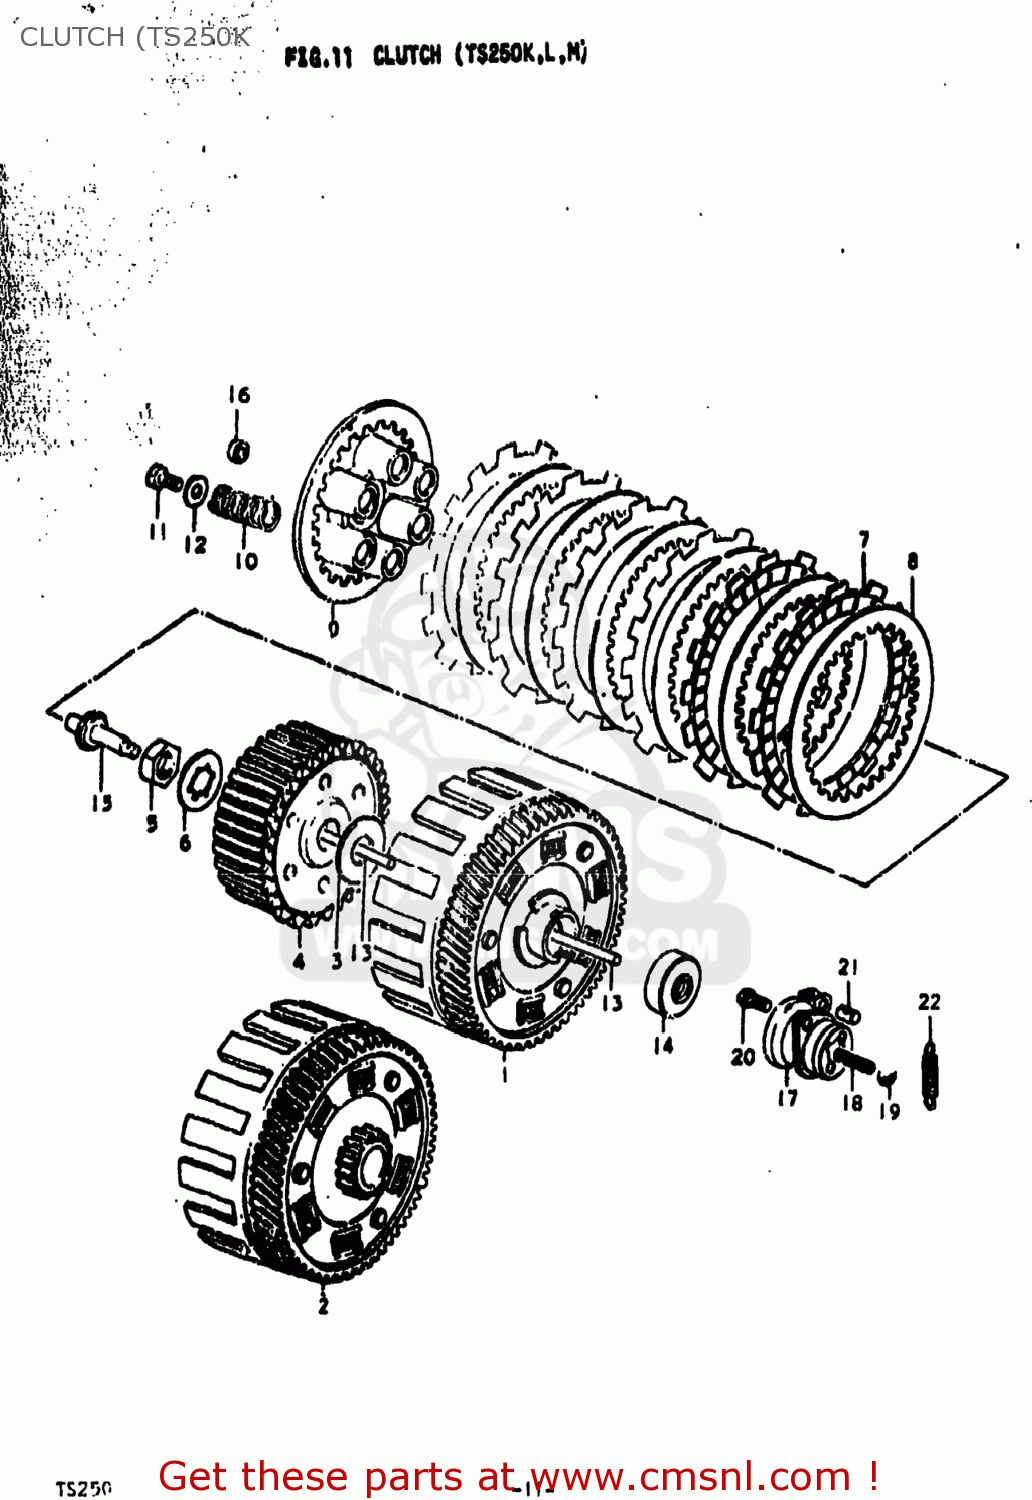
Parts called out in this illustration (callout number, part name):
1	GEAR ASSEMBLY,PRIMARY DRIVE
2	GEAR ASSEMBLY,PRIMARY DRIVE
3	WASHER(20X44X3)
4	HUB,CLUTCH SLEEVE
5	NUT (20MM)
6	WASHER,LOCK
7	PLATE,CLUTCH DRIVE (MCA)
8	PLATE,CLUTCH DRIVEN(T:2.0) (NAS)
9	DISC,CLUTCH PRESSURE
10	SPRING
11	BOLT
12	WASHER
13	ROD,CLUTCH PUSH
14	SEAL,OIL (6X30X5)
15	ROD,CLUTCH RELEASE
16	SEAL,OIL (10X17X5)
17	SCREW ASSEMBLY,CLUTCH RELEASE
18	SCREW
19	NUT
20	SCREW 6X12
21	PIECE,RELEASE ARM END
22	SPRING
